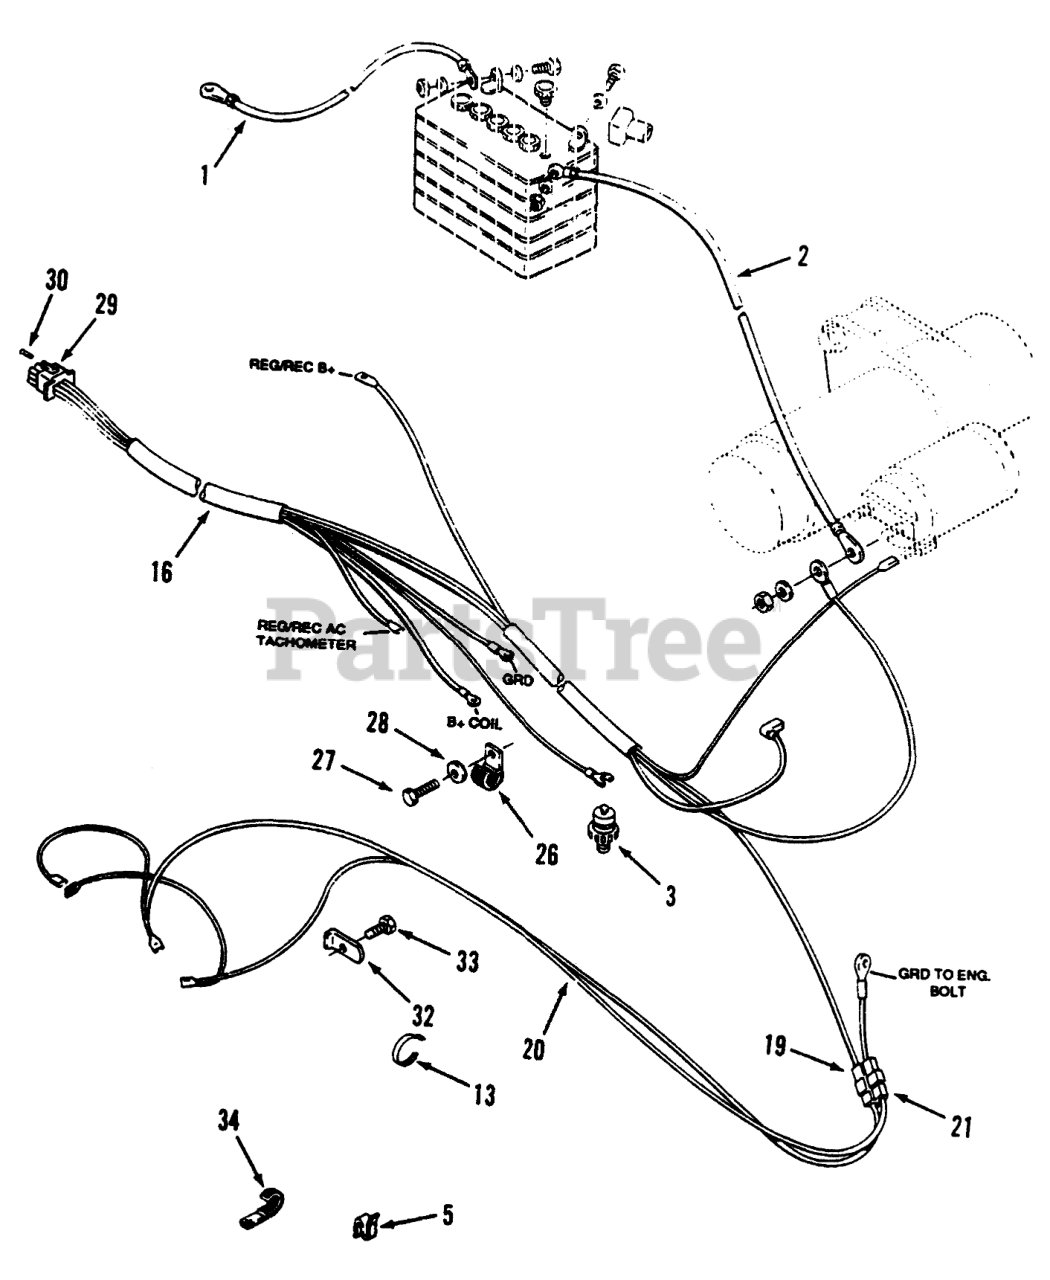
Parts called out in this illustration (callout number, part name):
1	Cable-Battery Ground
2	ASS'Y-WIRE
3	SWITCH - OIL PRESSURE
4	Boot
5	SPEED CLIP
13	PLASTIC TIE
16	Engine Wiring Harness
19	MALE CONNECTOR
20	HARNESS-HEADLIGHT
21	CONNECTOR BODY
26	Clip
27	SCREW-HWH
28	LOCKWASHER 1/4 IT
29	CONNECTOR CAP
30	CONTACT SOCKET
32	LOCK-HEADLIGHT
33	SCREW-HWH
34	CLIP
